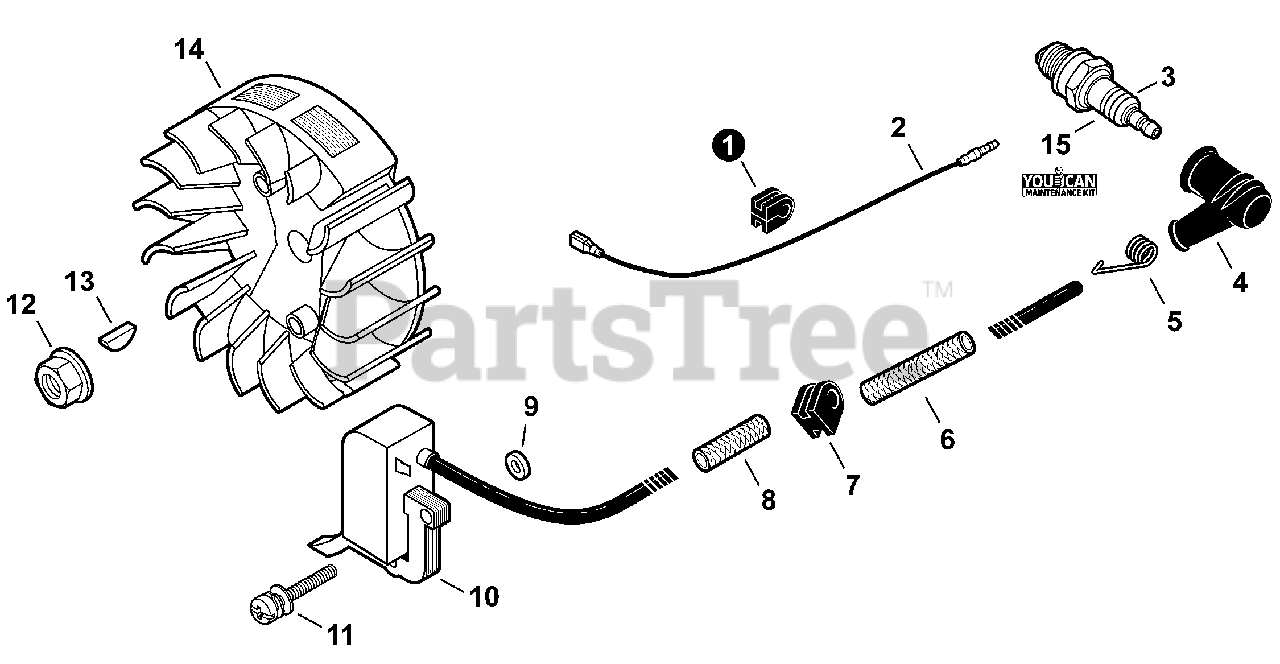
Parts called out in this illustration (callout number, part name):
2	LEAD - IGNITION
3	SPARK PLUG - BPMR8Y
4	CAP, SPARK PLUG
5	TERMINAL, SPARK PLUG
6	TUBE, INSULATOR 7×8.6×50
8	TUBE, INSULATOR 7×8.6×30
9	WASHER 5.2×12×3
10	COIL, IGNITION
11	SCREW 5×18
12	NUT, FLANGE M8
13	KEY, WOODRUFF
14	FLYWHEEL
15	TUNE-UP KIT - YOUCAN™
